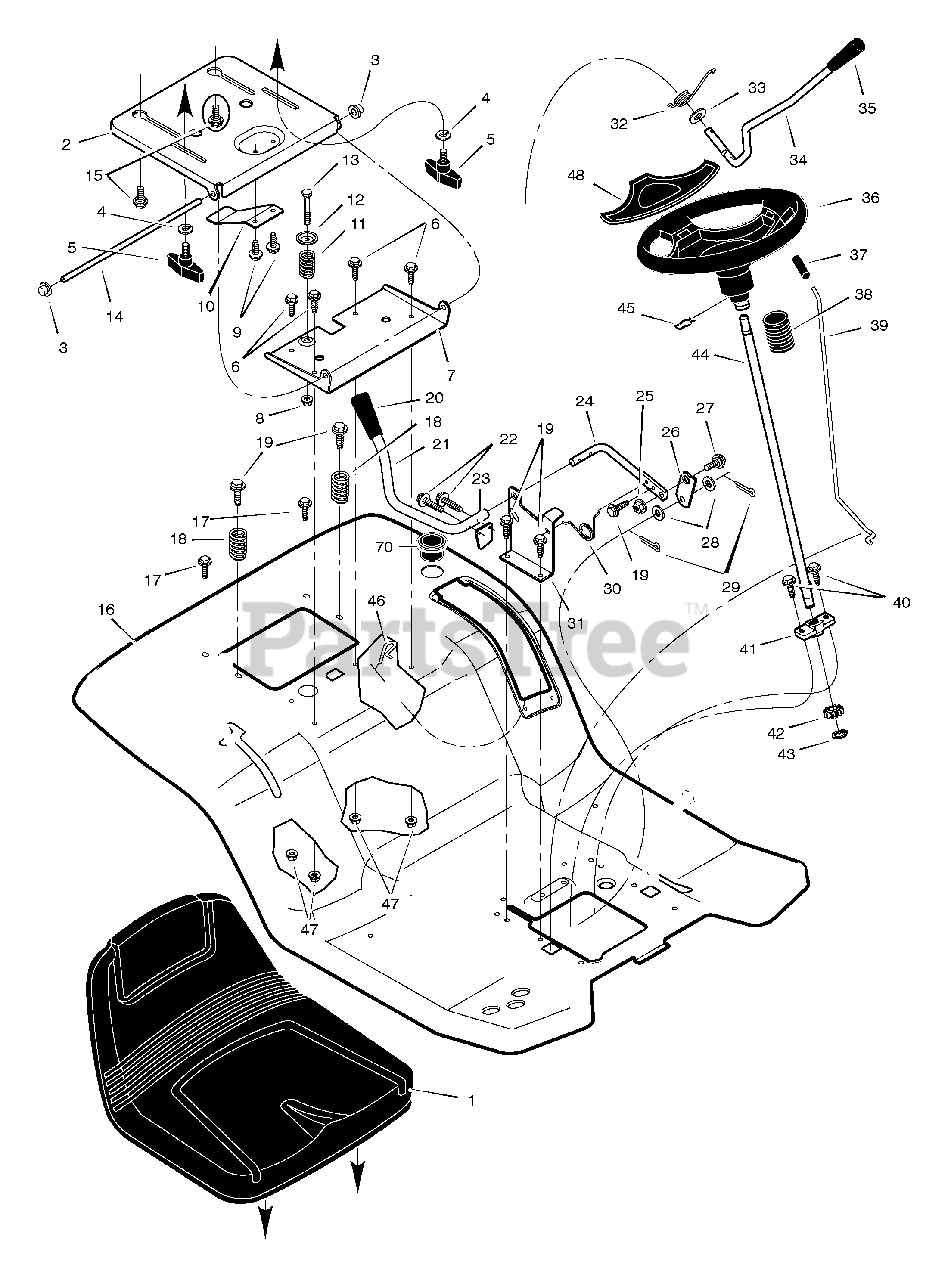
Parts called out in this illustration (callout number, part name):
1	Seat
2	Support, Seat
3	Push-On Cap
4	Washer
5	Bolt, Wing
6	Bolt
7	Bracket, Pivot
10	Spring, Leaf
11	Spring
12	Washer, Cup
14	Rod, Pivot
15	Bolt, Shoulder
16	Deck, Seat
20	Grip
21	Handle, PTO
22	Screw, Hex
23	Paddle, Switch
24	Lever, PTO
25	Nut
26	Link, PTO
27	Shoulder, Bolt
29	Pin, Cotter
31	Bracket, PTO
34	Handle, Lift
35	Grip
36	Wheel, Steering
38	Bellows
39	Rod, Parking Brake
41	Bearing, Lower
42	Gear, Pinion
43	Retainer
44	Shaft, Steering
45	Clip, Retainer
46	Pin, Cotter
47	Nut
48	Cover, Steering Wheel
70	Holder, Beverage
